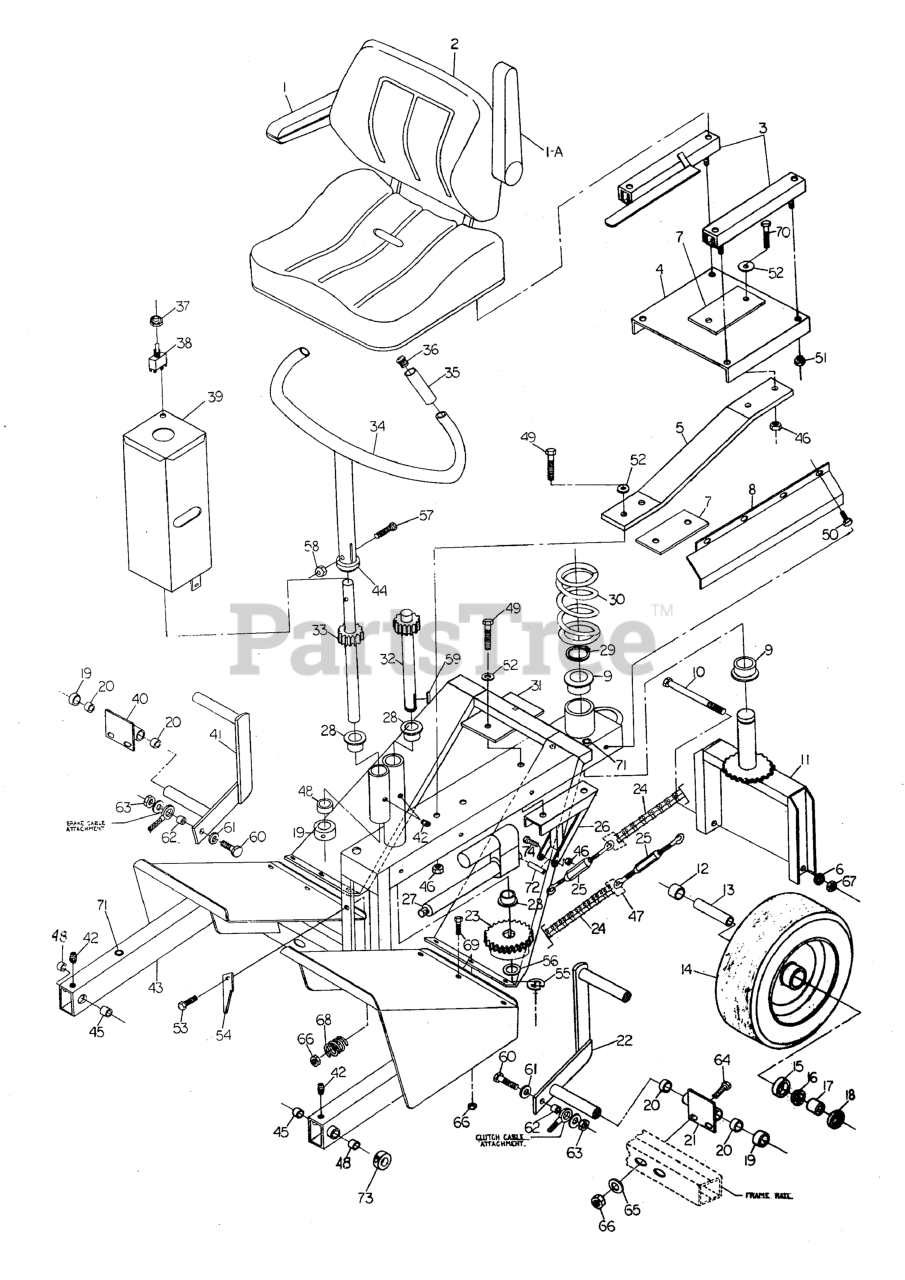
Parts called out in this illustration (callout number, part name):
1	ARM REST, RH
1A	ARM REST, LH
3	SEAT ADJUSTER RAILS (set of 2)
4	Seat Plate Weldment
5	SEAT SPRING
6	5/8 Lock Washer
7	SUPPORT, Seat Plate
8	Chain Guard Left
9	BUSHING, FLANGE
10	BOLT, 5/8-11 x 9-1/2
11	Steering Wheel Mount Weldment
12	SPACER, 1.00 x 1.25 x 1.53
13	Steering Wheel Sleeve
14	Steering Tire Assembly
14	Tire Only
14	Rim Only
15	BEARING CUP
16	BEARING, Tapered Roller
17	Steering Tire Spacer
18	GREASE SEAL
19	COLLAR, 3/4" Set
20	BUSHING
21	Clutch Pedal Bracket Weldment
22	Clutch Pedal Weldment
23	40B 24 x 3/4 Sprocket
24	CHAIN, #40 Roller, 43 Links
25	Turnbuckle
26	Actuator Mount Weldment
27	Electric Actuator
28	BUSHING, Flange
29	SNAP RING, External
30	Compression Seat Spring
31	Frame Support Weldment
32	Steering Shaft Weldment
33	Steering Handle Shaft Weldment
34	STEERING HANDLE
35	GRIP, Foam
36	End Plug
37	Toggle Boot
38	Toggle Switch
39	Steering Gear Guard
40	Brake Pedal Bracket
41	Brake Pedal Weldment
42	GREASE FITTING
43	Rider Frame Weldment
44	COLLAR, 1" Split
45	BUSHING
46	3/8 Serrated Flange Nut
47	CONNECTOR, #40 Chain Link
48	BUSHING, Brass
49	3/8-16 x 3-1/2 GD 5 Bolt
50	1/4-20 x 5/8 GD 5 Bolt
51	5/16-18 Serrated Flange Nut
52	3/8 Flat Washer
53	5/8-18 x 2 GD 5 Bolt
54	Brake Lever
55	C-CLIP
56	SHIM
57	3/8-16 x 1-1/2 GD 5 Bolt
58	3/8 Lock Nut
59	KEY, 3/16 SQ. X 7/8
60	1/4-20 x 1-1/2 GD 8 Bolt
61	1/4 Flat Washer
62	SPACER, .26 X .38 X .50
63	1/4 Lock Nut
64	5/16-18 x 2-1/2 GD 5 Bolt
65	5/16 Flat Washer
66	5/16-18 Nut
67	5/8 Nut
68	SPRING, Compression
69	5/16-18 x 1 GD 5 Hex Head Cap Screw
70	3/8-16 x 1-1/4 GD 5 Bolt
71	Snap Bushing
72	Actuator Spacer
73	COLLAR, 3/4" Split
74	3/8-16 x 2 GD 5 Bolt
